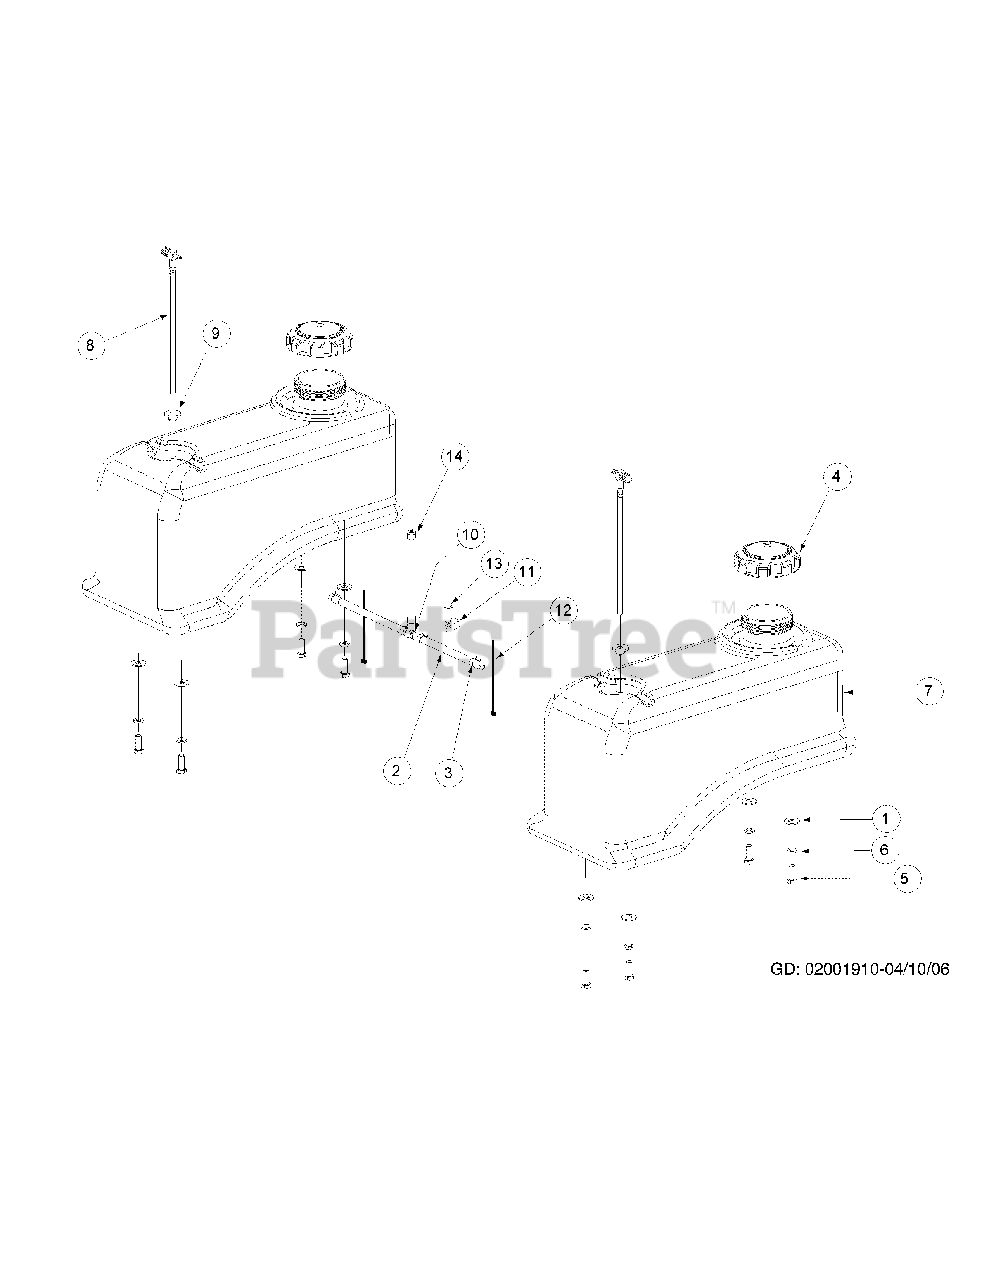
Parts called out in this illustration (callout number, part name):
1	Flat Washer, .406 ID, 1.0 OD, .105
2	Hose, 1/4" Fuel Line (79.5 in inches)
3	Clamp, Union
4	Fuel Cap, 3.5
5	Hex, Cap Screw, 3/8-16, .88
6	Lock Washer, 3/8
7	Fuel Tank
8	Fuel Fitting
9	Grommet, Fuel Tank
10	Tee Fitting, Fuel
11	Clamp, 1/2 Tubing
12	Cable Tie
13	Flat Washer, 1.4 x .630 x .0515
14	Hose Clamp, SAE #4: 1/4-5/8, SS
